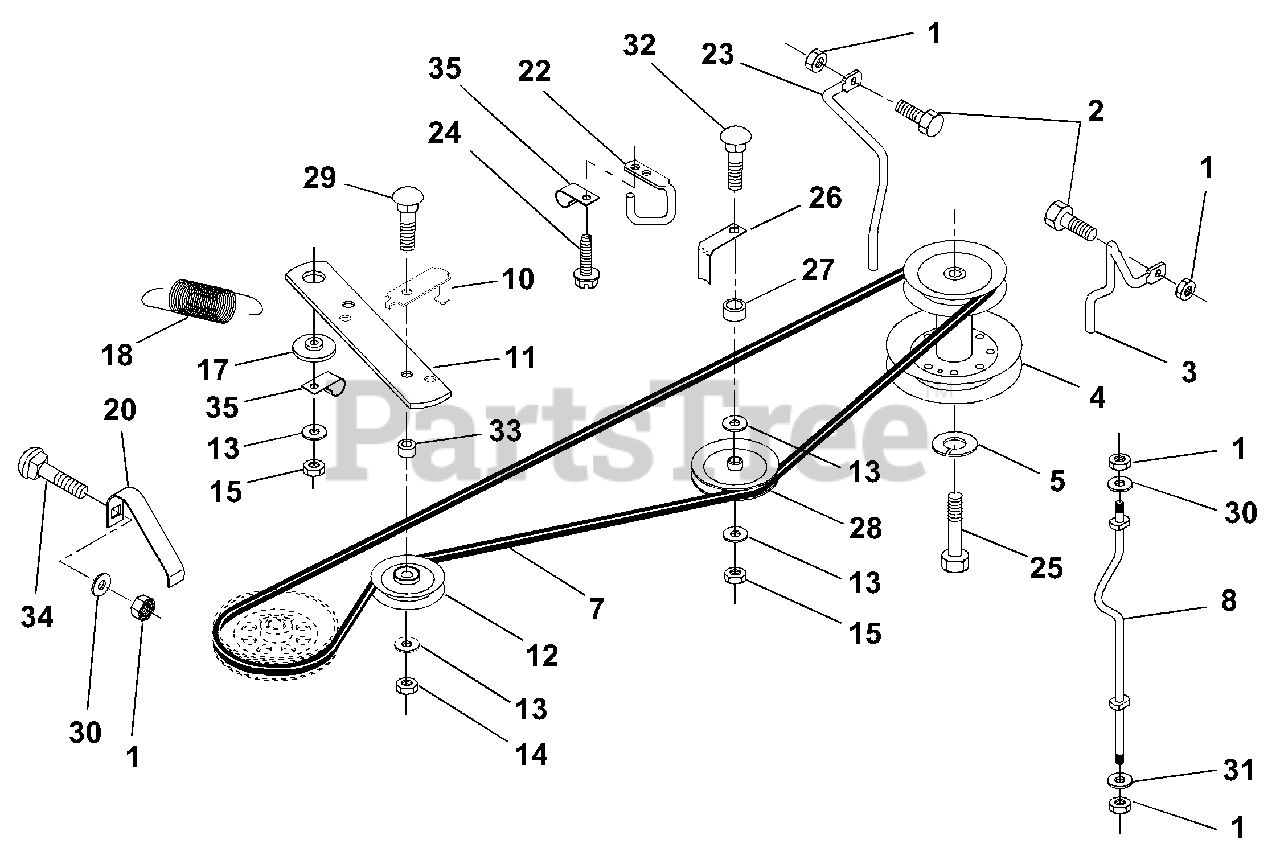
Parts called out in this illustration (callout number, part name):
1	Nut, Lock Hx w/Ins 5/16-18
2	Bolt, Hex Head 5/16-18 x 3/4
3	Keeper, Belt RH Front
4	Pulley, Engine
5	Washer, Lock 7/16
8	Keeper, Belt RH
10	Keeper,Belt, Idler Pulley
11	Arm, Idler
12	Idler, Flat
13	Washer 13/32 x 13/16 x 16 Gauge
14	Nut, Centerlock 3/8-16
15	Nut, Crownlock 3/8-16
17	Spacer, Retainer
18	Spring, Extension
20	Keeper,Belt LH
22	Keeper Frame Ground Drive Belt
23	Keeper,Belt LH Front
24	Screw, Thd. Cut. 1/4-20 X 1/2
25	Bolt, Hex 7/16-20
26	Keeper, Belt
28	Pulley, V-Idler
29	Bolt, RDHD SQ 3/8-16 x 2-1/4
30	Washer Nut Lock Hex w/Ins. 5/6-18
31	Washer 11/32 x 3/4 x 16 Ga.
32	Carriage Bolt
34	Carriage Bolt
35	Clip Insulator
